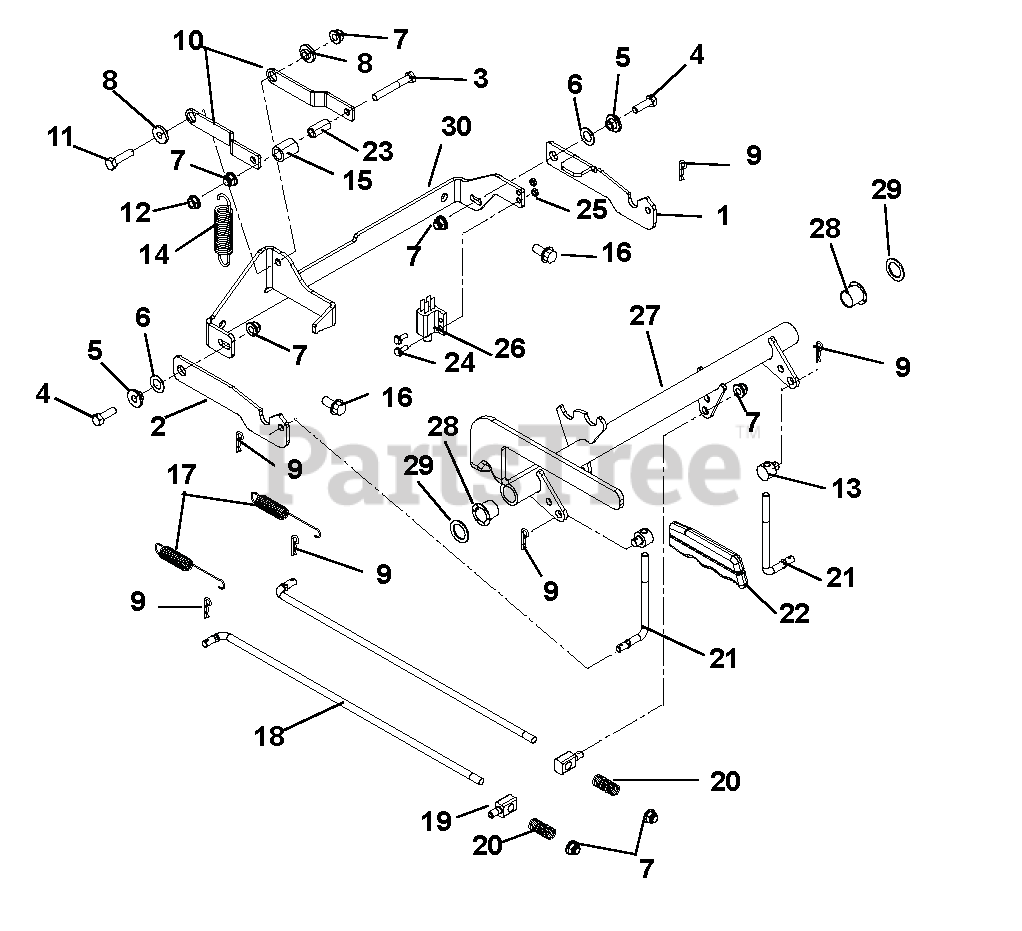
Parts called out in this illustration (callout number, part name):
1	LINK, BRAKE INTERLOCK
2	INTERLOCK, BRAKE
3	@BLT-HEX .31-18X2.25 GR5 YWZC
4	@BLT-HEX .31-18X1.00 GR5 YWZC
5	BSHG-FLG .32X.500X.344X.880
6	WSHR-FL-STL .505X.875X.024 YWZ
7	@NUT-LK-NYL-FLG .31-18 YWZC
8	BSHG, FLG .325X.499X.26X.88
9	PIN-HAIR INT .08X.18X1.18 YWZC
10	ARM, BRAKE CAM
11	@BLT-HEX .31-18X1.25 GR5 YWZC
12	@NUT-LK-TOP-FLG .31-18 YWZC
13	TRUNNION, BRAKE .31-18 UNC
14	SG-TENS .105X.812X3.88 WLD 15
15	ROLLER, CAM LOCK
16	@SCR-TAP .38-16X.75 HWH TR YWZ
17	SG-TENS .056X.60X4.40
18	ROD, PARK BRAKE
19	PIN, PIVOT/TRUNNION
20	SPRING, COMPRESSION
21	LINK, INTERLOCK BRAKE
22	GRIP, PARKING BRAKE (YELLOW)
23	BSHG, SPCR .330X.500X1.01 PM
24	SCR-MCH.25-20X.50 FLTCNTRSK SS
25	@NUT-LK-NYL 10-24 W/INSRT YWZC
26	SWITCH- DOUBLE POLE N.O./N.O.
27	SHAFT, BRAKE
28	BUSHING, IGLIDE CLIP
29	WSHR-FL-STL.754X1.125X.062YWZC
30	BRKT, BRAKE MTG
